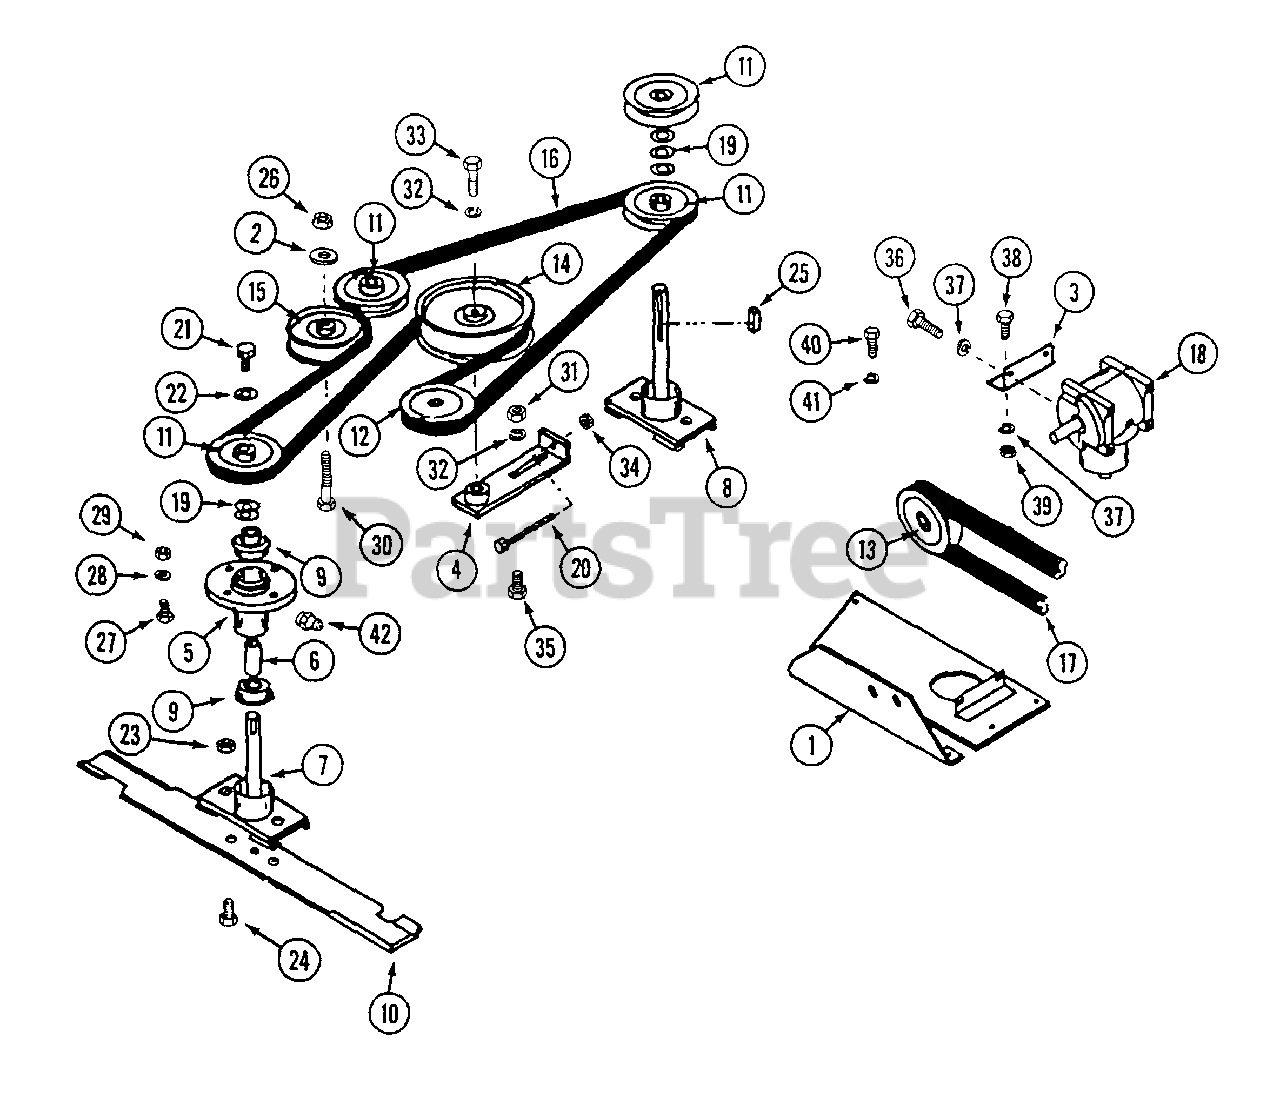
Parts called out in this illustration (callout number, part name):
1	MOUNT - gear box
2	WASHER - 3/8"
3	ANGLE - gear box mount
4	TIGHTENER - belt
5	HOUSING ASSEMBLY - spindle
6	SPACER spindle
7	SHAFT - spindle, short
8	SHAFT - spindle, long
9	BEARING - spindle
10	BLADE - mower
11	PULLEY - spindle
12	PULLEY - gear box output
13	PULLEY - gear box input
14	PULLEY - idler, large
15	PULLEY - idler, small
18	GEAR BOX - angle drive
19	SPACER - washer
20	BOLT - 1/4" - 20 x 4"
21	BOLT - 3/8" - 24 x 1-1/4"
22	WASHER - 3/8" - 10 ga.
23	NUT - lock 3/8" - 16
24	BOLT - 3/8" - 16 x 1"
25	KEY - 3/16" x 1"
26	NUT - 3/8" flange lock
27	BOLT - 7/16" - 14 x 1-1/4"
28	LOCKWASHER - 7/16"
29	NUT - 7/16" - 14
30	BOLT - 3/8" - 16 x 2-1/4"
31	NUT - 3/8"
32	LOCKWASHER - 3/8"
33	BOLT - 3/8" - 16 x 1-1/4"
34	NUT - 1/4" - 20 lock
35	BOLT - 3/8" - 16 x 1" carriage
36	BOLT - 5/16" - 18 x 3/4"
37	LOCKWASHER - 5/16"
38	BOLT - 5/16" - 18 x 3/4"
39	NUT - 5/16" - 18
40	BOLT - 1/4" - 20 x 1/2"
41	LOCKWASHER - 1/4"
42	FITTING - grease 1/4" - 28
